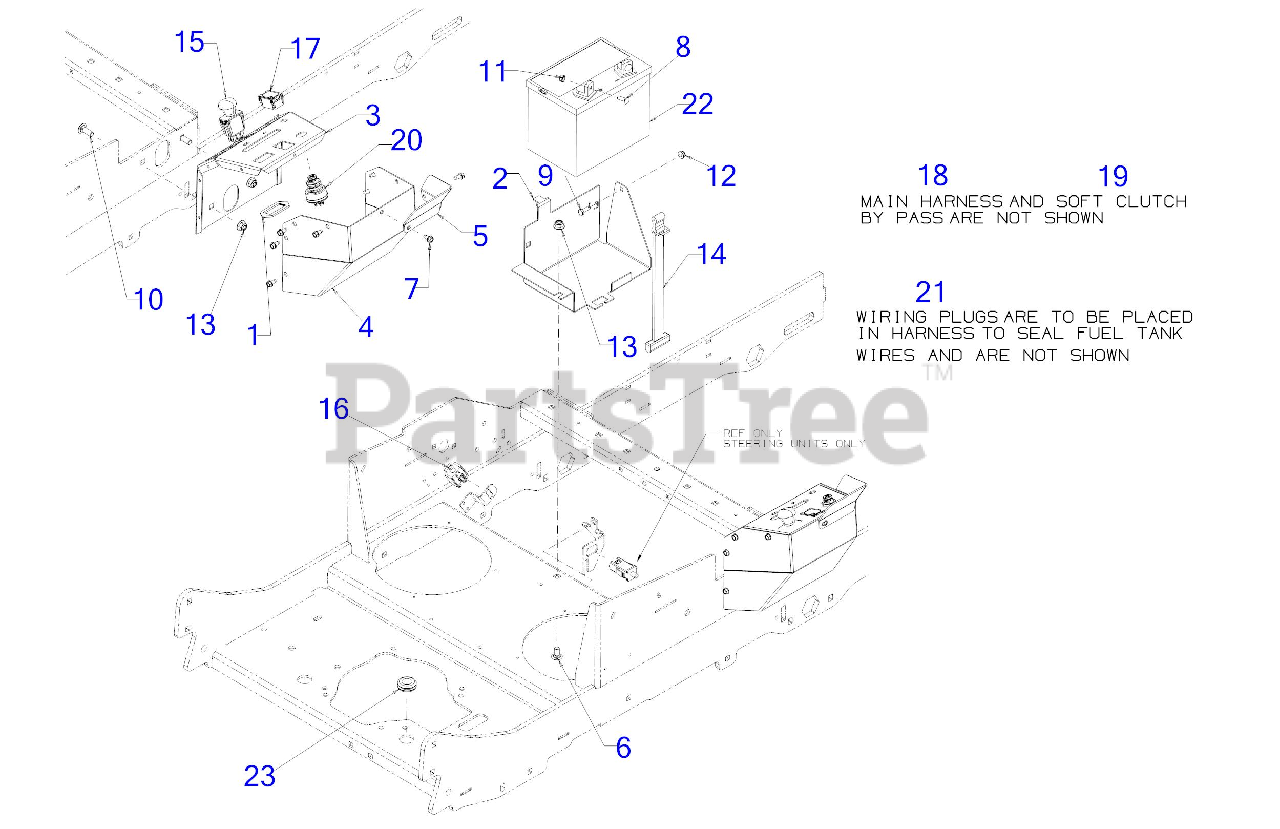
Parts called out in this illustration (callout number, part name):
1	BRACKET-PTO SWITCH
6	CARRIAGE BOLT 3/8-16 x .750 GR5
7	SCREW 1/4-20 X.500
8	SCREW 1/4-20 x .75 GR5
9	SCREW 1/4-20X.75 GR5
10	CARRIAGE BOLT 3/8-16 x 1.00 GR5
11	SEMS NUT 1/4-20
12	FLANGE LOCK NUT
14	BATTERY RETAINER STRAP
15	PTO SWITCH (BLACK KNOB) TEXT SYM
16	3 POLE SWITCH ( NC-NO-NO)
17	HOUR METER
18	WIRE HARNESS ASSEMBLY KOH/KAW EFI
19	BYPASS HARNESS
20	KEY SWITCH (3 POSITION) (Add 925-06908)
21	SEALED CAP ASSEMBLY
23	RUBBER GROMMET
